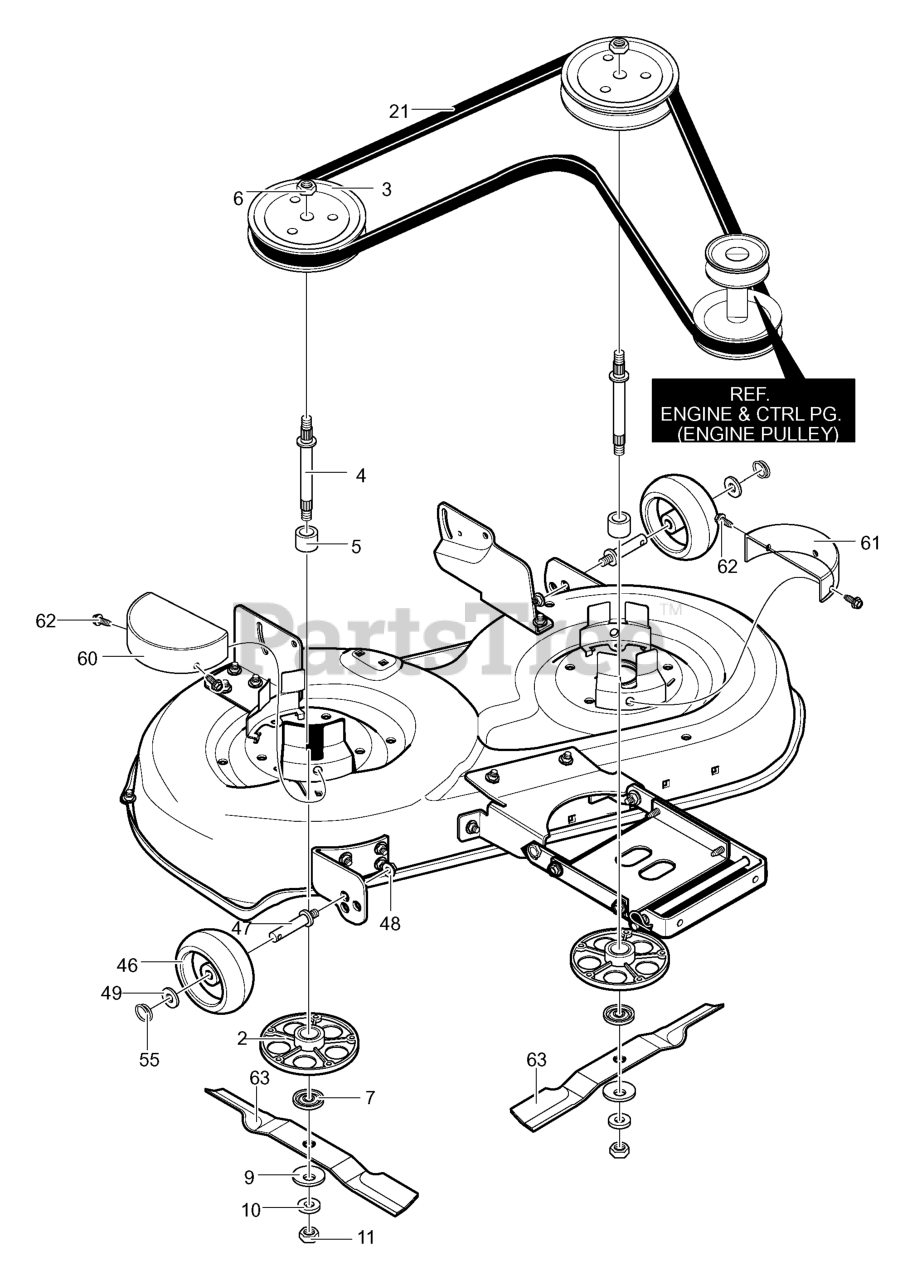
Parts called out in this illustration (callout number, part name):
2	Jackshaft Assembly
3	Pulley, Split
4	Jackshaft
5	Spacer, .625x.875x1.85
6	Nut, 9/16-18
7	Adapter, Deck/Blade
11	Nut, .56-18 Regular
21	Belt, 42" Deck
46	Gauge Wheel
47	Bolt, SPSH 3/8-16
48	Nut, 3/8-16 Wdfllk
49	Flat washer
55	Circle Pin
60	GUARD, Belt R.H.
61	GUARD, Pulley L.H.
62	Screw, 1/4-20x.63
63	Blade, 42" Low Lift
